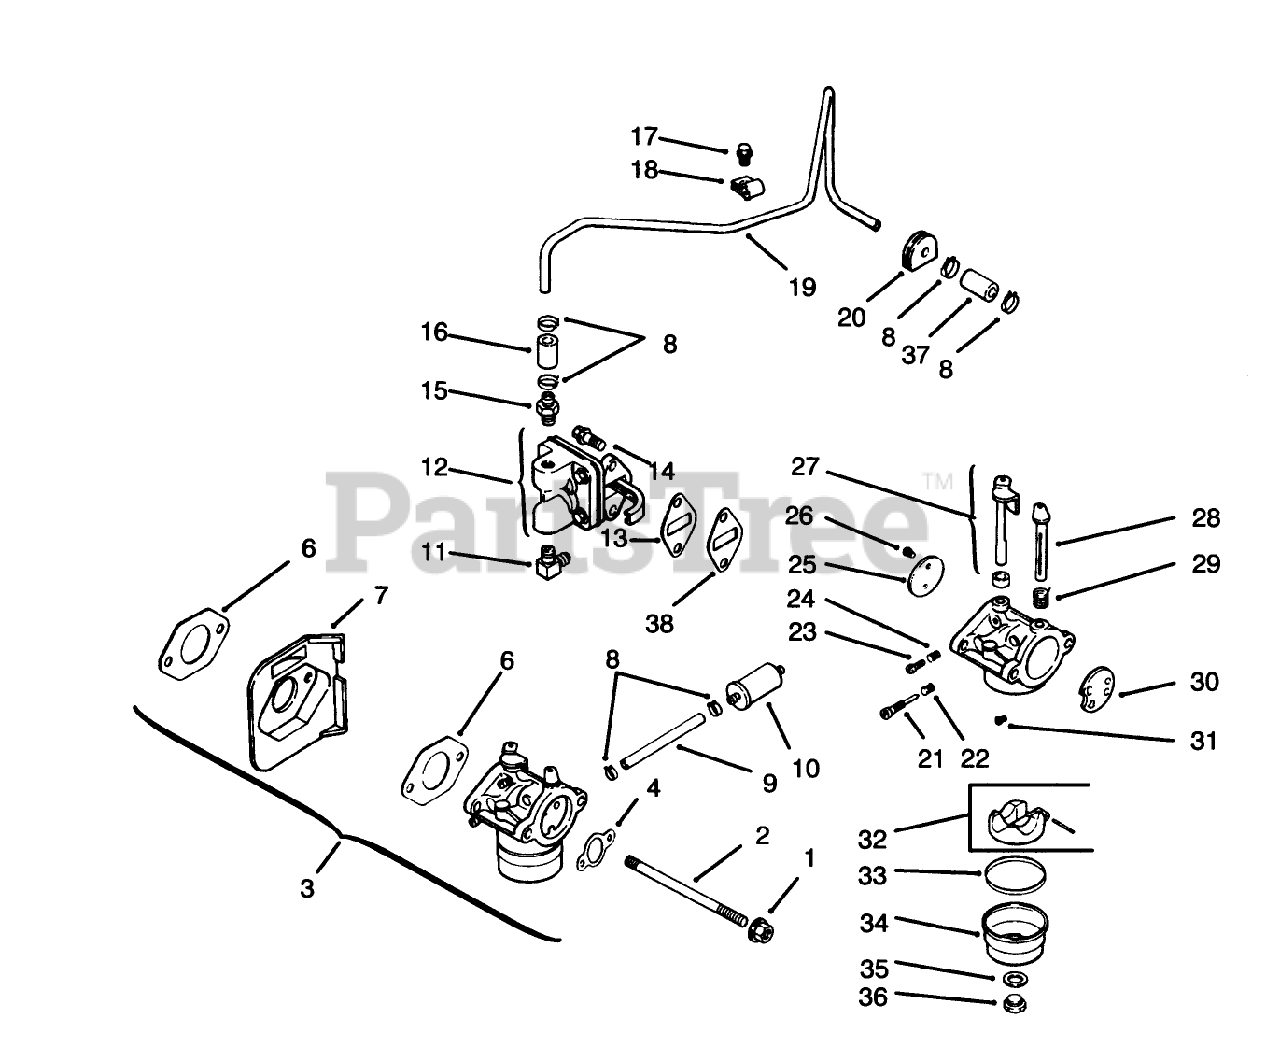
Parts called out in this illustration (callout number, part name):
2	Stud M6x1.0x110 (Only On: 72042,72043,72062,72063)
4	Gasket-Air Cleaner (Only On: 72042, 72043, 72062, 72063)
5	Carurator ASM Incl 21-36
6	Gasket-Carburetor (Only On: 72042, 72063, 72062, 72043)
7	Deflector-Heat
8	Clamp
9	Line-Fuel
10	Filter-Fuel (Only On: 72042,72043,72062,72063)
11	Connector
12	Kit-Pump INCL 13-14 (Only On: 72042,72043,72062,72063)
13	Gasket-Fuel Pump (Only On: 72042,72043,72062,72063)
14	Screw
15	Connector
16	Line-Fuel 1.25 Inch (Only On: 72042,72043,72062,72063)
18	Clamp-Fuel Line (Only On: 72042, 72063, 72062, 72043)
19	Line-Fuel
20	Grommet (Only On: 72042, 72063, 72062, 72043)
21	Needle-Idle Fuel Adjust
22	Spring-Idle Fuel (Only On: 72042, 72063, 72062, 72043)
23	Screw-Idle Speed Adjust (Only On: 72042,72043,72062,72063)
24	Spring-Idle Fuel (Only On: 72042, 72063, 72062, 72043)
25	Plate-Throttle (Only On: 72042,72043,72062,72063)
26	Screw-Throttle Plate (Only On: 72042,72043,72062,72063)
27	Shaft-W/Lever Seal (Only On: 72042, 72063, 72062, 72043)
28	Shaft-Choke (Only On: 72042. 72063, 72062, 72043)
29	Spring-Choke Return (Only On: 72042,72063, 72062, 72043)
30	Plate-Choke (Only On: 72042, 72063, 72062, 72043)
31	Jet-Main
32	Kit-Float (Only On: 72042,72043,72062,72063)
33	Gasket-Bowl (Only On: 72042,72043,72062,72063)
34	Bowl-Fuel (Only On: 72042, 72063, 72062, 72043)
35	Gasket-Bowl Screw (Only On: 72042, 72063, 72062, 72043)
36	Screw-Fuel Bowl (Only On: 72042, 72063,72062, 72043)
37	Line-Fuel 3" (Only On: 72042, 72063, 72062, 72043)
38	Spacer-Fuel Pump
